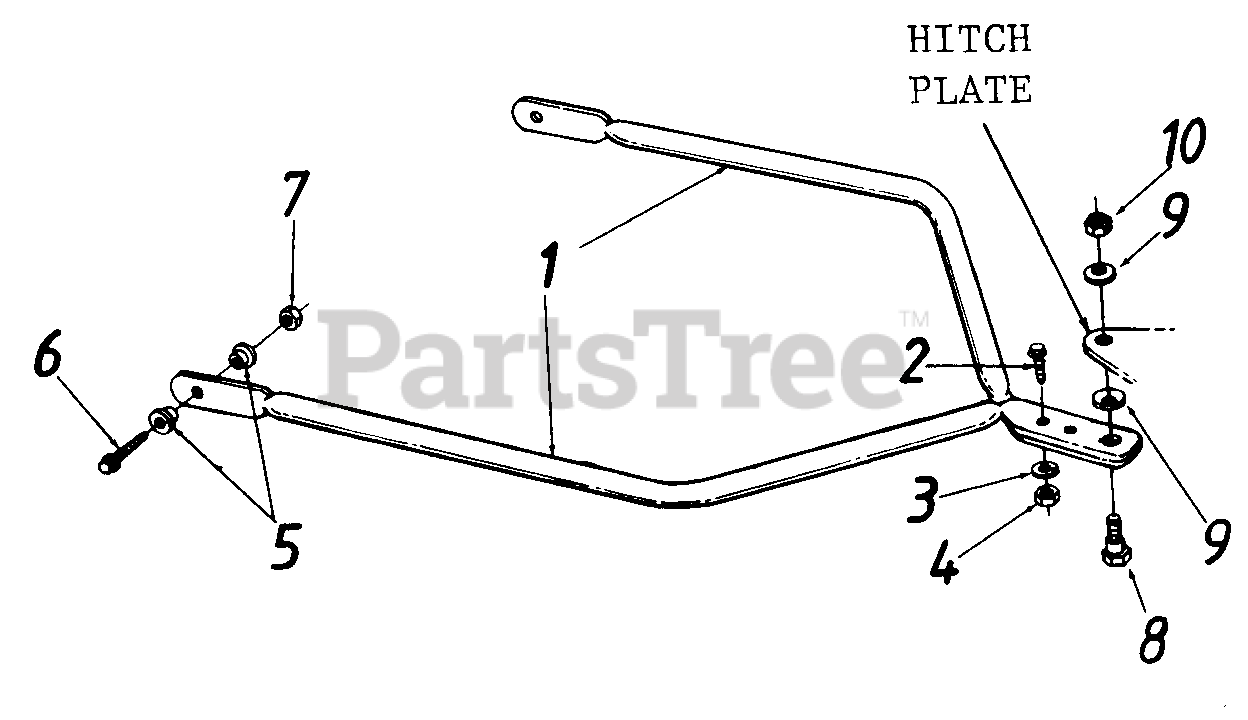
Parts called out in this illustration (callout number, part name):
3	L.-Wash. 1/4" I.D.*
4	Hex Nut 1/4-20 Thd.*
5	Shoulder Spacer
6	Hex Wash. Hd. Self-Tapp Scr. 5/16-18 x 1.0" Lg.*
7	Hex Nut 5/16-18 Thd.*
8	Shoulder Bolt
9	Bell-Wash. .39" I.D. x 1.12" O.D.
10	Hex Top Jam Nut 3/8-16 Thd.
